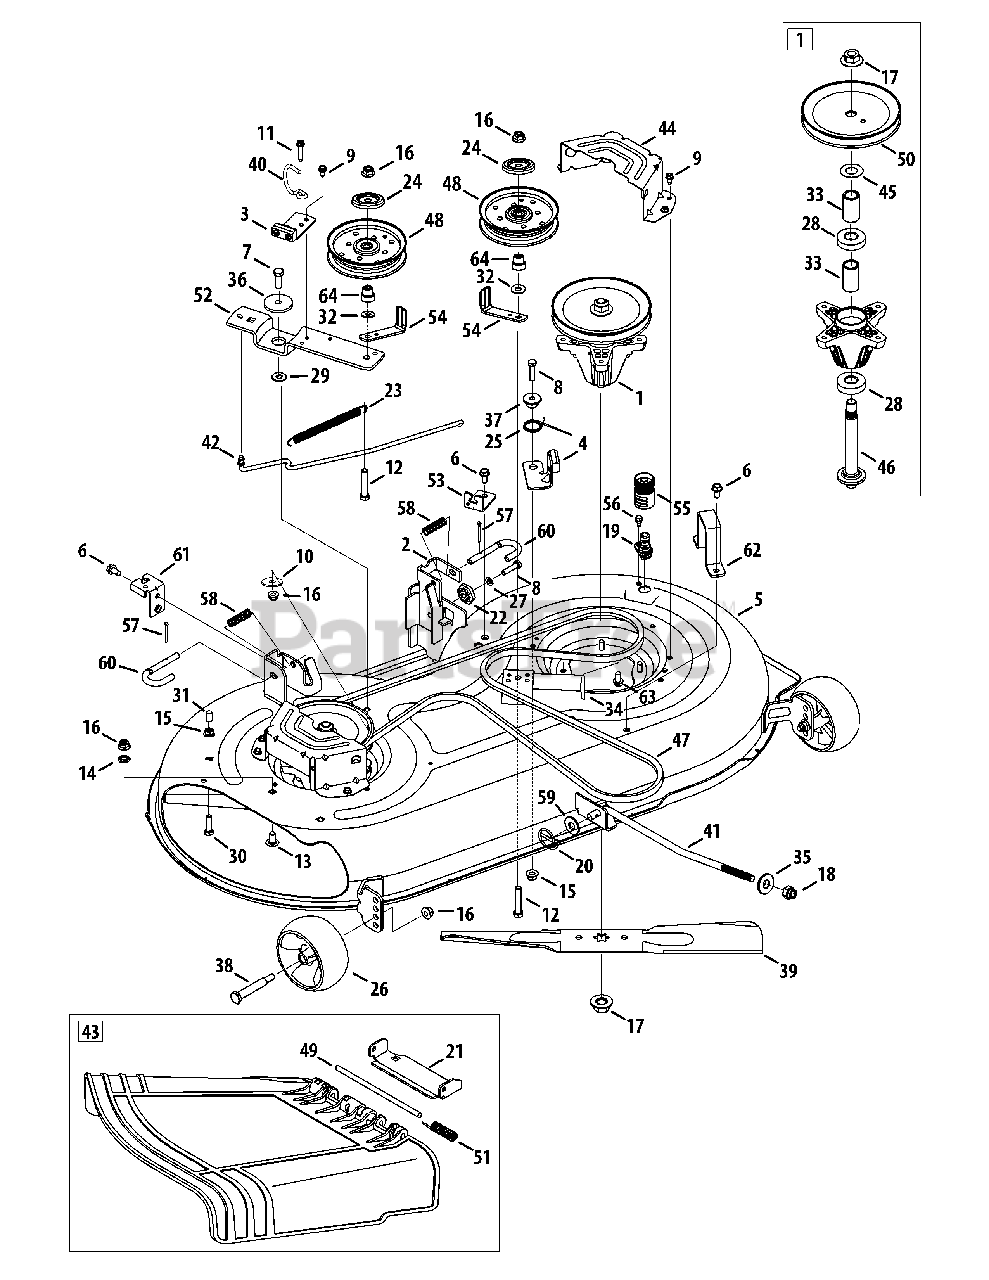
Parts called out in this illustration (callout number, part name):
1	Pulley Spindle Ass’y 6.3 dia.
2	Deck Hanger Bracket Ass’y LH
3	Deck Brake Assembly
4	Deck Brake Assembly
5	Deck, 42" w/o wheels
6	S-Tapp Scr 5/16-18 x .75
7	Hex Screw, 3/8-16, 1.25, Gr5, Std
8	Hex Wash Tap Scr 5/16-18 x 1.25
9	Hex Wash S-Tapp Scr 1/4-20 x .50
10	Flat Washer .406 x 1.5 x .105
11	Hex Bolt 1/4-20 x .75
12	Hex. Hd. Cap Scr. 3/8-16 x 2.0 Gr. 5
13	Carriage Bolt 3/8-16 x .75 Gr. 1
14	Push Nut, 3/8
15	Hex Flange Locknut 5/16-18 Gr. F, Nylon
16	Hex Flange Locknut 3/8-16 Gr. F, Ny lon
17	Hex Flange Locknut 5/8-18
18	Hex Locknut 1/2-13
19	Deck Water Nozzle
20	Lynch Pin
21	Chute Bracket
22	Deck Gear Adjuster
23	Extension Spring .62 dia. x 6.12 Lg.
24	Pulley Cap
25	Torsion Spring .992 ID x 1.17 OD
26	Deck Wheel 5.0 Dia.
27	L-Wash 5/16 ID
28	Ball Bearing .787 ID x 1.85 OD x .551
29	Flat Washer .385 x 1.0 x .030
30	Hex Cap Screw 5/16-18 x 1.0
31	Cap .290 x .50
32	Flat Washer .385 ID x .870 OD x .092
33	Spacer .792 x 1.060 x 1.860
34	Deck Support Stationary Idler Brkt.
35	Cupped Washer .63 x 1.25 x .18
36	Shoulder Spacer .8540 x .200
37	Shoulder Spacer .50 x .145
38	Shoul der Bolt .496 x 2.5, 3/8-16
39	Blade, 21.23", 2-in-1
40	Belt Keeper Rod
41	Front Lift Deck Rod
42	Brake Control Rod
43	Side Discharge Chute Assembly
44	Deck Belt Cover, 42
45	Flat Washer .760 ID x 1.5 OD
46	Spindle Shaft 6.11" Lg.
47	V-Belt
48	Idler Pulley w/Flange 4.25 Dia.
49	Hinge Pin .3125 diam. x 7.96" Lg.
50	Deck Pulley 6.3 dia.
51	Torsion Spring .44 ID x 2.0
52	Idler Pivot Bracket
53	Deck Cable Engagement Bracket
54	Belt Guard Pulley Bracket
55	Water Nozzle Adapter
56	Shoulder Screw 1/4-20 x 0.50
57	Cotter Pin 1/8 x 1.25
58	Compression Spring .535 OD x 1.751" Lg.
59	Flat Washer .531 ID x 1.25 OD x .100
60	Deck Release Pin
61	Cable Bracket Deck Engage
62	Deck Lift Pivot Cup
63	Hex. TT Screw 5/16-18 x .75
64	Idler Shoulder Spacer
